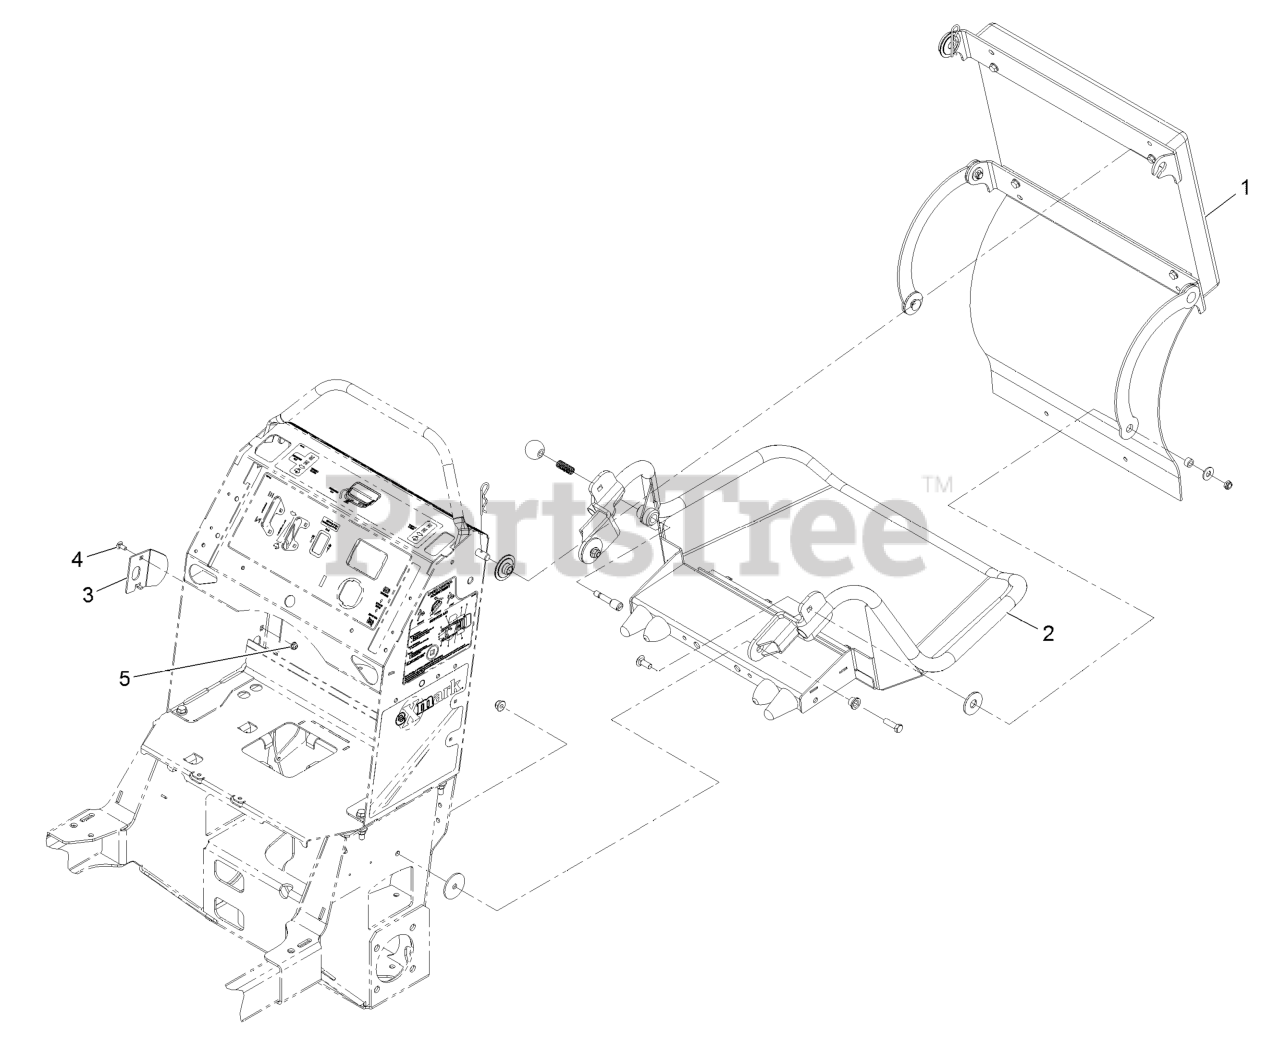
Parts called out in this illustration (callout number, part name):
2	PLATFORM ASM
3	PLATE-STRIKER
4	SCREW-CARR
